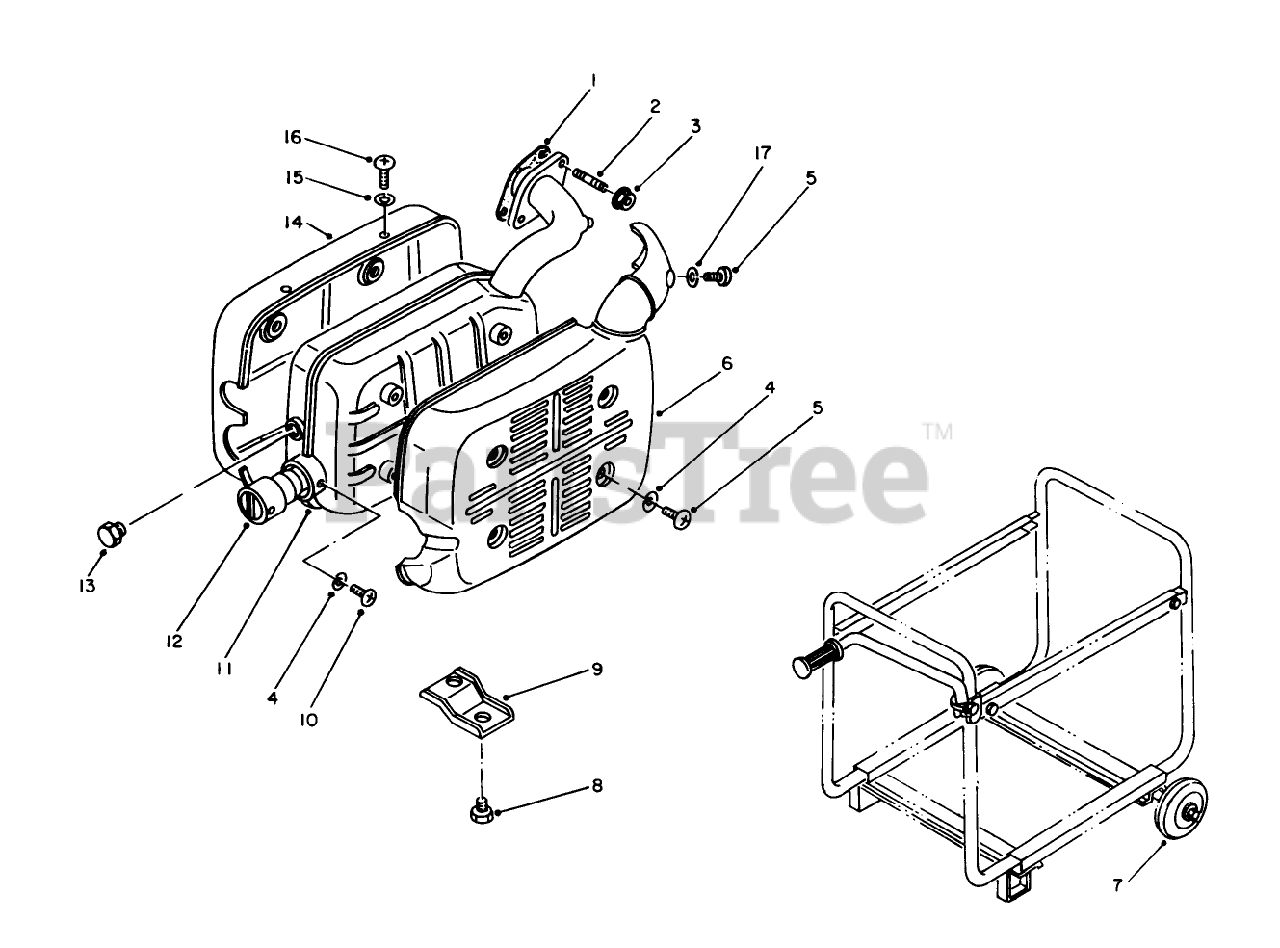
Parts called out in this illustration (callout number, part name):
1	Gasket-Exhaust
2	Stud Bolt
4	LOCKWASHER
5	SCREW
6	Cover-Front
7	Wheel Assembly (Optional)
9	Bracket-Muffler
10	Screw
11	MUFFLER ASSM
12	Cleanout Tube
13	Drain Plug
14	Cover-Rear
15	Lockwasher
16	Screw
17	LOCKWASHER
